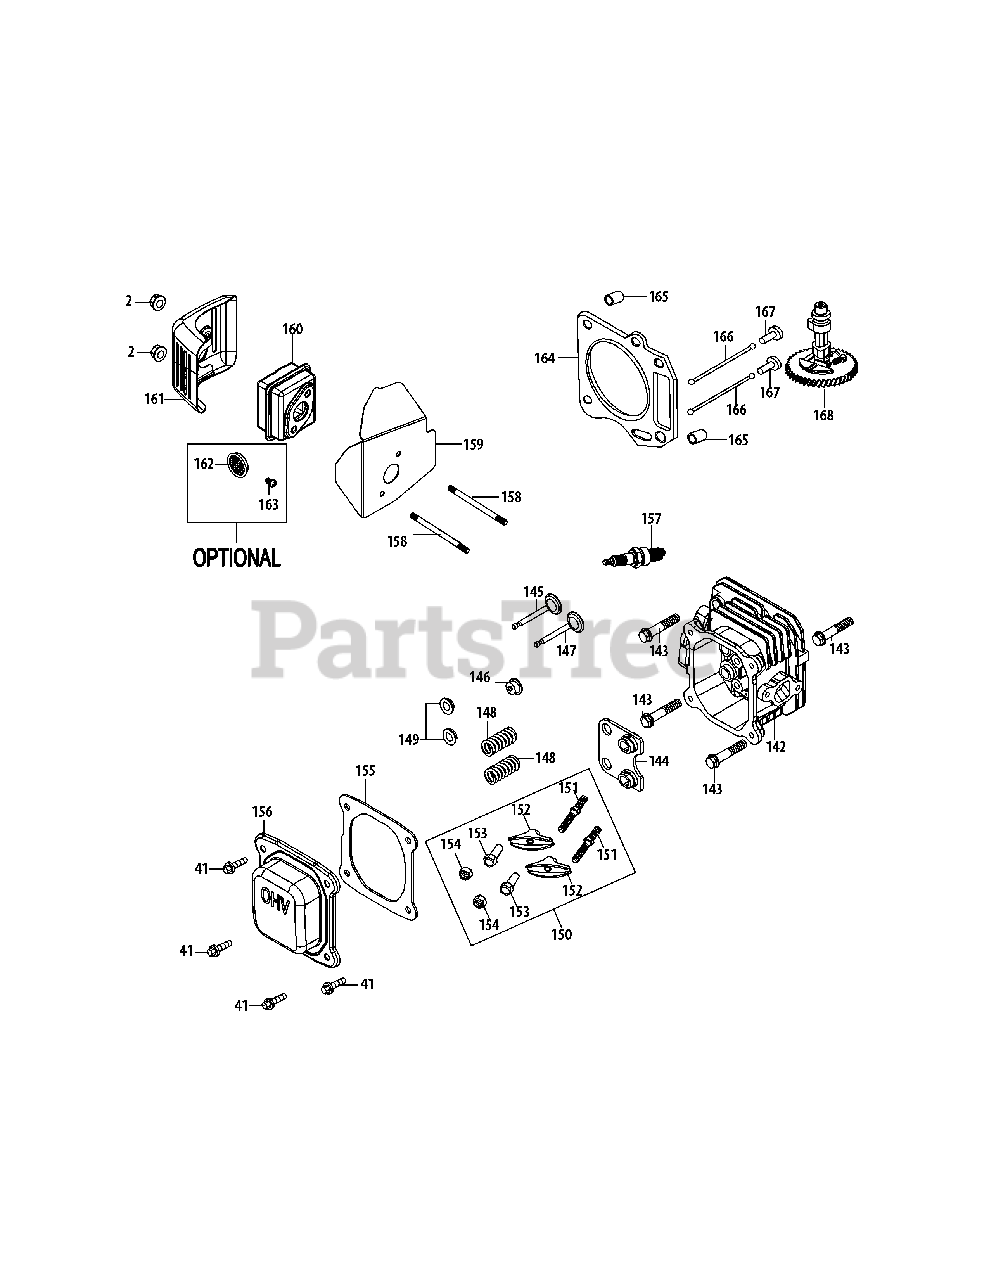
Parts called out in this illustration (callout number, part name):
2	Nut M6 X 10 Mm
41	Bolt M6×14
142	Cylinder Head
143	Head Bolt M8×54
144	Push Rod Guide
145	Intake Valve
146	Intake Valve Seal
147	Exhaust Valve
148	Valve Spring
149	Valve Spring Retainer
150	Rocker Arm Assembly
151	Rocker Arm Stud
152	Rocker Arm
153	Fulcrum Nut
155	Valve Cover Gasket
156	Valve Cover
157	Spark Plug
158	Muffler Stud M6X68
158	Muffler Stud Assembly
159	Muffler Gasket
160	Muffler Assembly
161	Muffler Shield
162	Spark Arrestor
163	Spark Arrestor Screw
164	Cylinder Head Gasket
165	Cylinder Head Dowel 10X16
168	Camshaft Assembly
